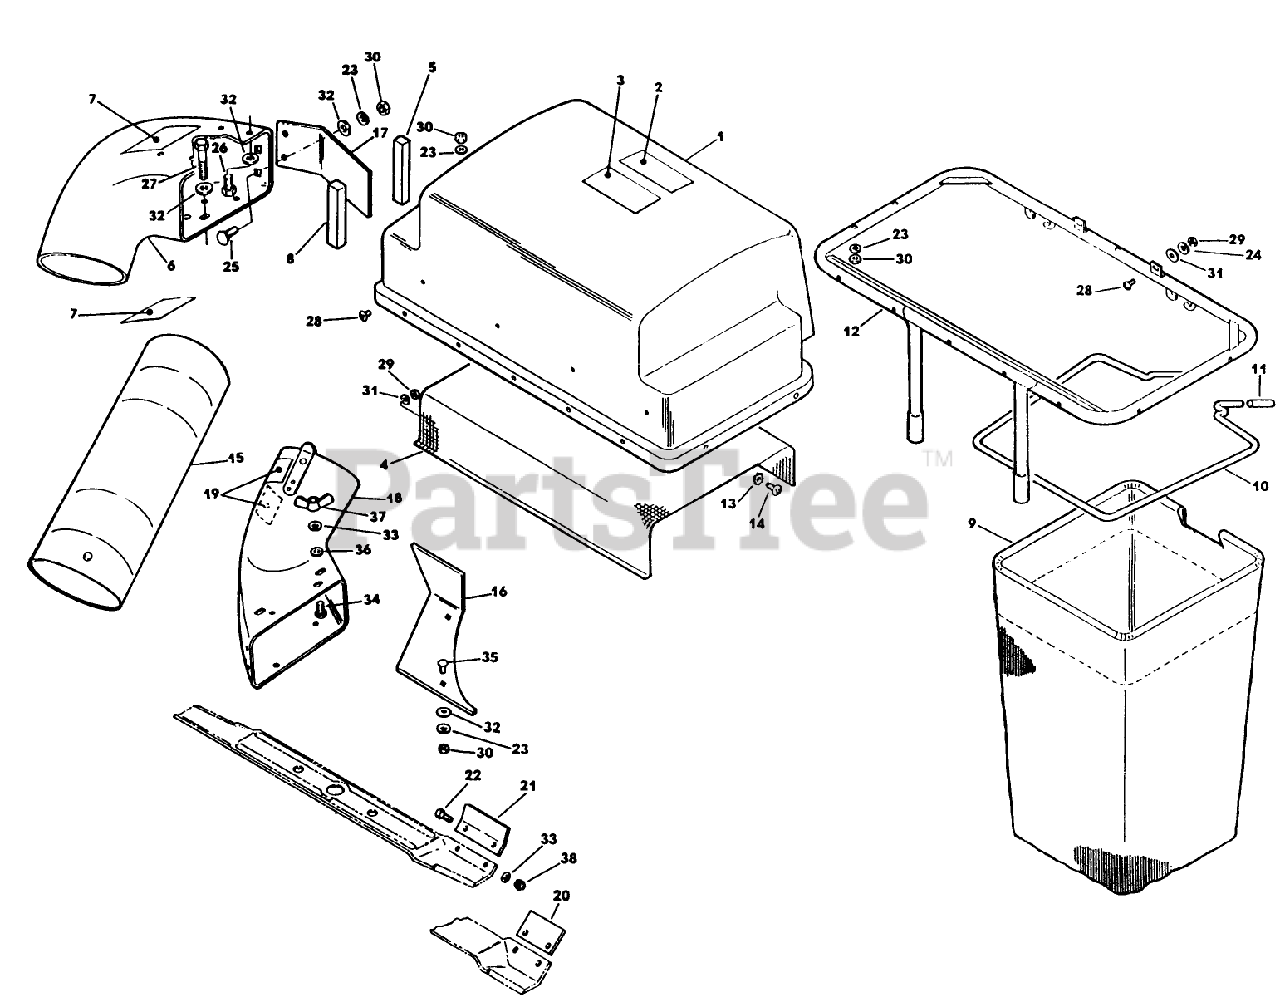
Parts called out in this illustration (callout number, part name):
1	COVER & STICKER AY
9	GRASS BAG
10	FRAME-GRASS BAG
16	DEFLECTOR-CHUTE
17	DEFLECTOR - GRASS
20	EXTENSION-BLADE
21	EXTENSION BLADE
22	SCREW - HEX
30	NUT
34	BOLT - CARRIAGE
38	NUT
